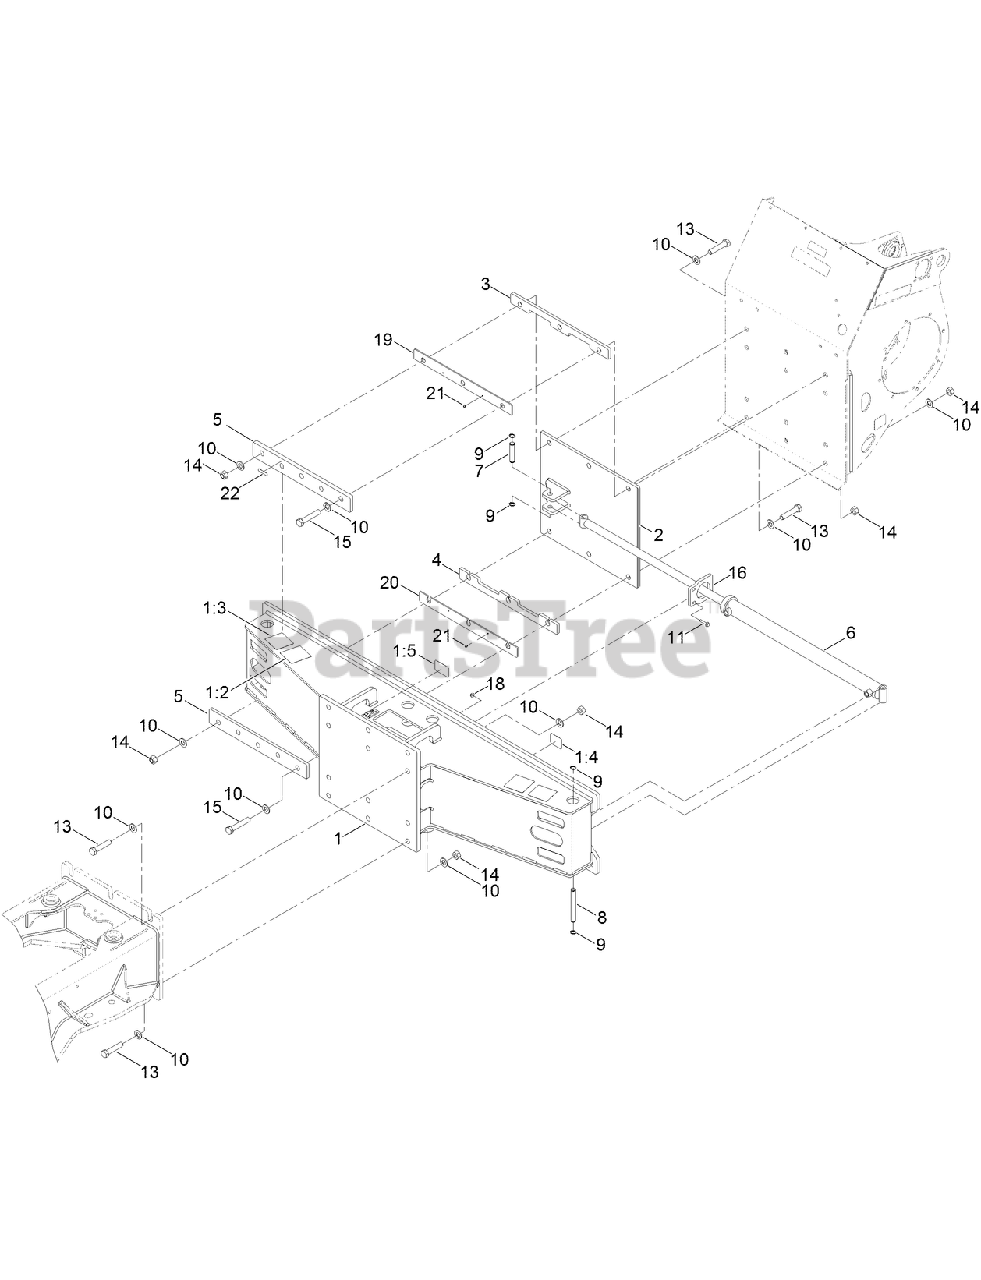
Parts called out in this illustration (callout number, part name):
1	SLIDING OFFSET FRAME
1:2	DECAL-WARNING, CRUSHING
1:3	DECAL-DANGER, CRUSHING
1:4	DECAL-TIE DOWN
1:5	DECAL-LIFT/TIE DOWN
2	SLIDE MOUNT ASM
3	PLATE-SPACER, UPPER
4	PLATE-SPACER, LOWER
5	PLATE-RETAINER
6	HYD CYLINDER ASM
7	PIN-CLEVIS
8	PIN-PLAIN
9	RING-RETAINING
10	WASHER-FLAT
11	SCREW-HHF
13	SCREW-HH
14	NUT-LOCK
16	PLATE-RETAINER
18	NUT-HF, NI
19	PLATE-SPACER, UPPER
20	PLATE-SPACER, LOWER
21	FITTING-GREASE, ZERK
22	DECAL-GREASE
